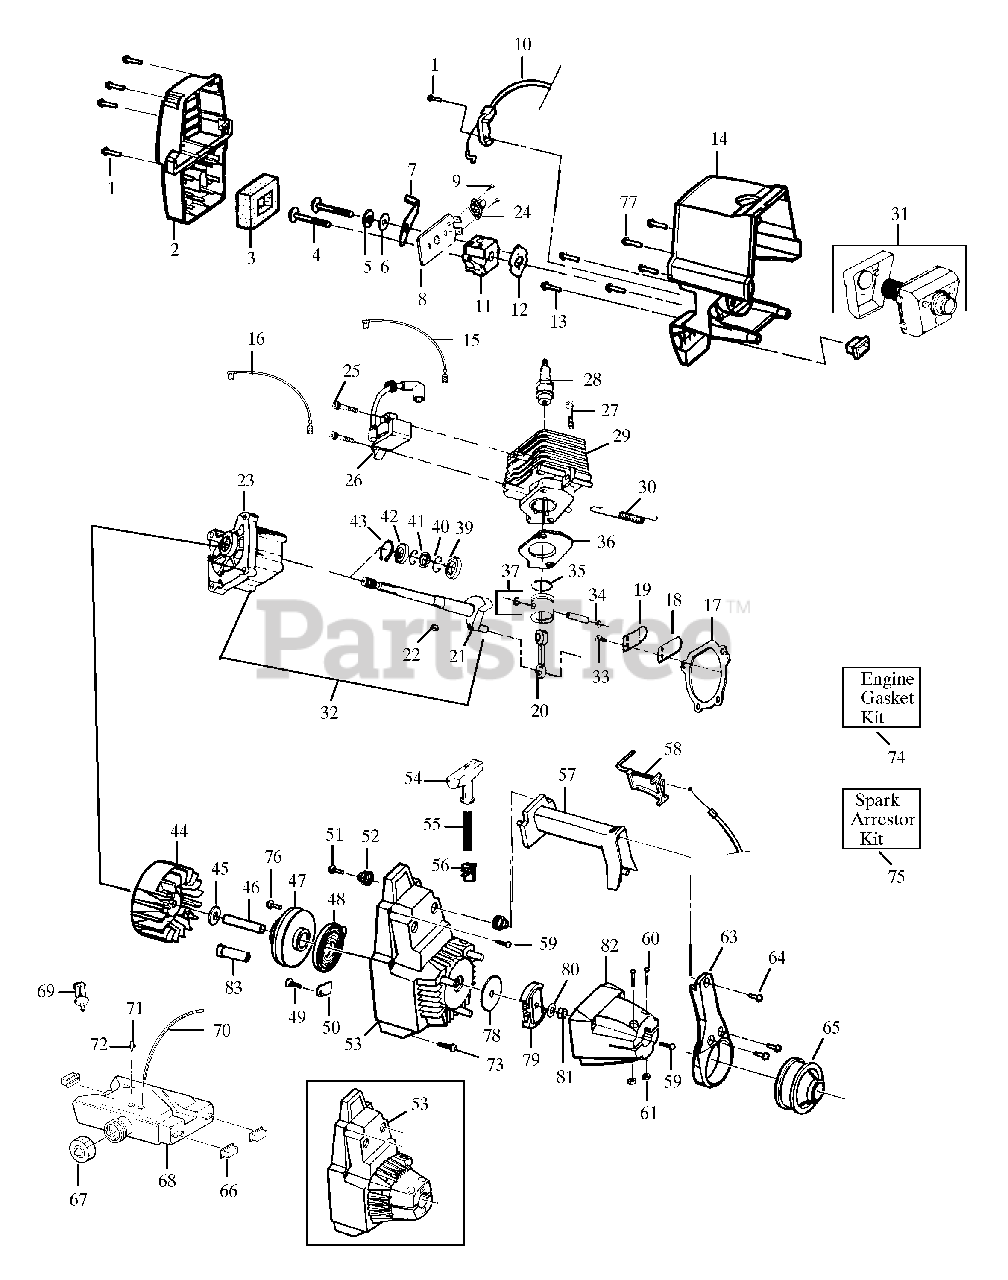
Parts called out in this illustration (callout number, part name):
2	Muffler/Air Box Cover
3	Air Filter Foam
6	Wave Washer
7	Choke Shutter
8	Air Filter Plate
10	Throttle Cable Ass'y.
11	Carburetor Model HP28P
11	Carburetor Model HP30SBP
12	Carburetor Gasket
15	Lead Wire Ass'y
16	Ground Wire Ass'y
17	Crankcase/Shroud Gasket
19	Reed Stop
20	Connecting Rod Ass'y.
21	Crankshaft Ass'y. Model HP28P
21	Crankshaft Ass'y. Model HP30SBP
22	Flywheel Key
23	Crankcase Ass'y.
24	Bulb Ass'y.
25	Screw
26	Ignition Module
28	Spark Plug
29	Cylinder
30	Muffler Attachment Spring
31	Muffler Kit
32	Crankcase & Crankshaft Ass'y Model HP28P
32	Crankcase & Crankshaft Ass'y Model HP30SBP
34	Piston Pin Retainer
35	Piston Ring
36	Cylinder Gasket
37	Piston Kit
39	Inner Bearing
40	Retaining Ring
41	Crankshaft Seal
42	Outer Bearing
43	Crankshaft Retaining Ring
44	Flywheel Ass'y. Model HP28P
44	Flywheel Ass'y. Model HP30SBP
45	Washer Model HP28P
45	Washer Model HP30SBP
46	Flywheel Spacer - Model HP30SBP
47	Starter Pulley Kit
48	Starter Spring
50	Retainer
52	Handle Isolator
53	Fan Housing Model HP28P
53	Fan Housing Model HP30SBP
54	Starter Handle
55	Rope Kit
56	Switch Model HP28P
56	Switch Model HP30SBP
63	Handle Cover
65	Isolator AV
65	Fuel Tank Ass'y. Units with primer bulb
66	Fuel Tank Isolator
67	Fuel Cap Ass'y.
68	Fuel Tank Ass'y. Non Primer units
69	Fuel Pickup Ass'y.
70	Fuel Line Kit Fuel Line
70	Fuel Line Kit Return Line
71	Check Valve
72	Retainer
74	Engine Gasket Kit
75	Spark Arrestor Kit
78	Clutch Washer - Model HP30SBP
79	Clutch Ass'y. Kit - Model HP30SBP
80	Washer - Model HP30SBP
81	Nut - Model HP30SBP
82	Clutch Housing - Model HP30SBP
83	Drive Coupling Model HP28P
